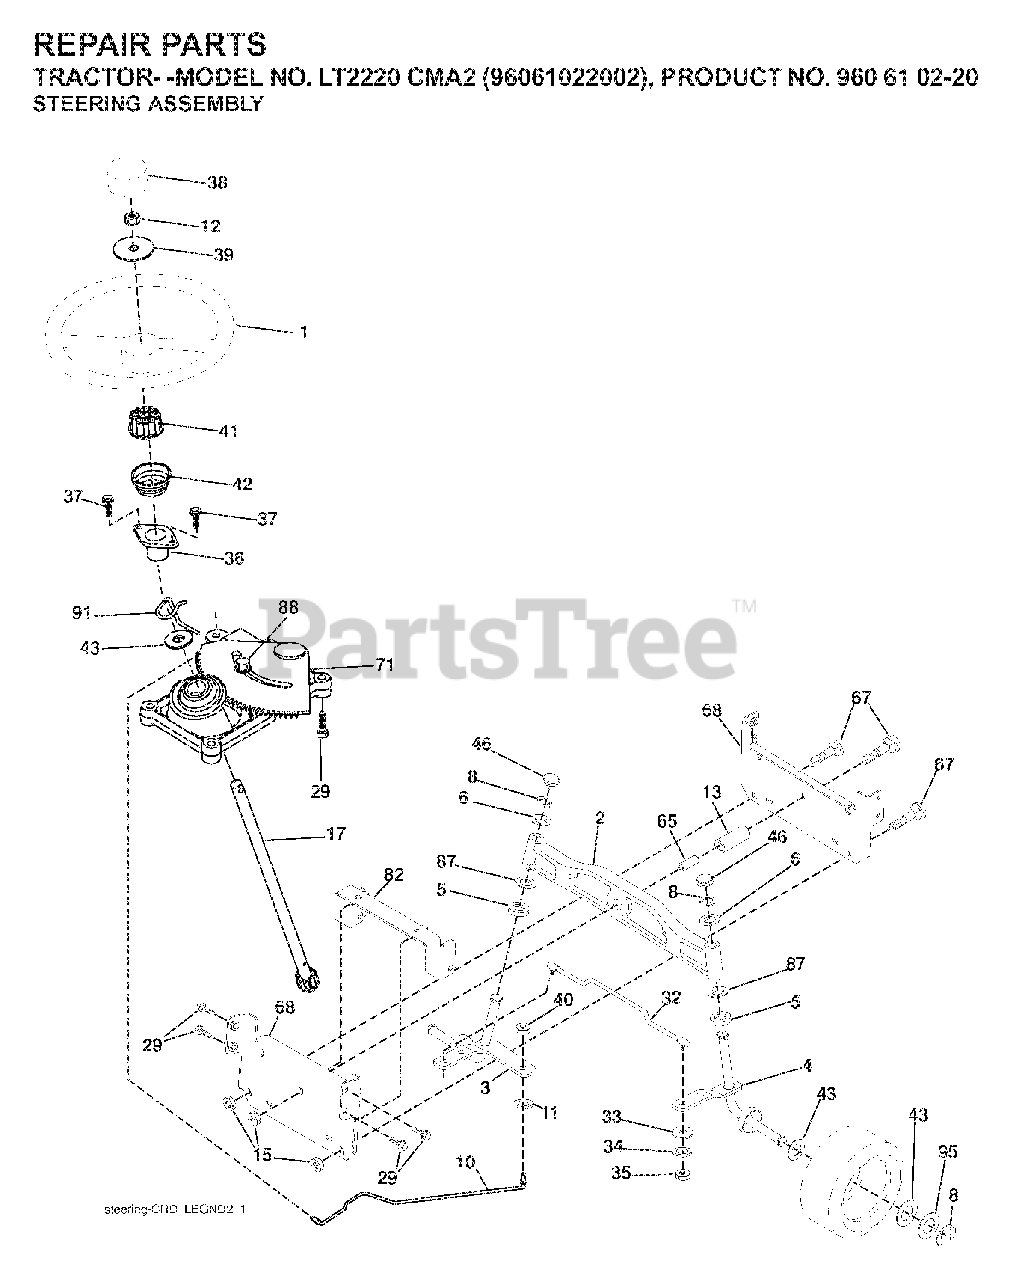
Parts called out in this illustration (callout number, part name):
1	WHEEL.STEERING.PREM.2.BLK
2	AXLE ASSY FRONT
3	SPINDLE.ASM.LH.15"TIRES
4	SPINDLE.ASM.RH.15"TIRES
8	RING CLIP
10	DRAGLINK.15".TIRES.2001
11	WASHER, LOCK 3/8
12	NUT.HEX.1/2-20
13	TUBE, PIVOT AXLE
15	NUT
17	SHAFT ASM STRG
29	SCREW, 3/8-16X3/4
33	WASHER M
34	LOCKWASHER
35	NUT, CROWNLOCK
36	BUSHING, STRG. BLK
38	INSERT.CAP.STRG.WH.BLACK
39	WASHER 9/16"ID, 2 3/8"OD
40	NUT CROWNLOCK 3/8-24
41	ADAPTER, WHEEL STNG..
46	CAP.SPINDLE
65	SPACER.BRACE.AXLE
67	BOLT CARRIAGE
68	BRACE.AXLE.15"TIRES
71	STEERING ASM
82	BRACKET.SUSP.CHASSIS.FRONT.15
87	WASHER, FLAT .781 X 1 1/2"
88	BOLT, SHOULDER 7/16-20
91	CLIP.STEERING
95	WASHER.HARDENED
